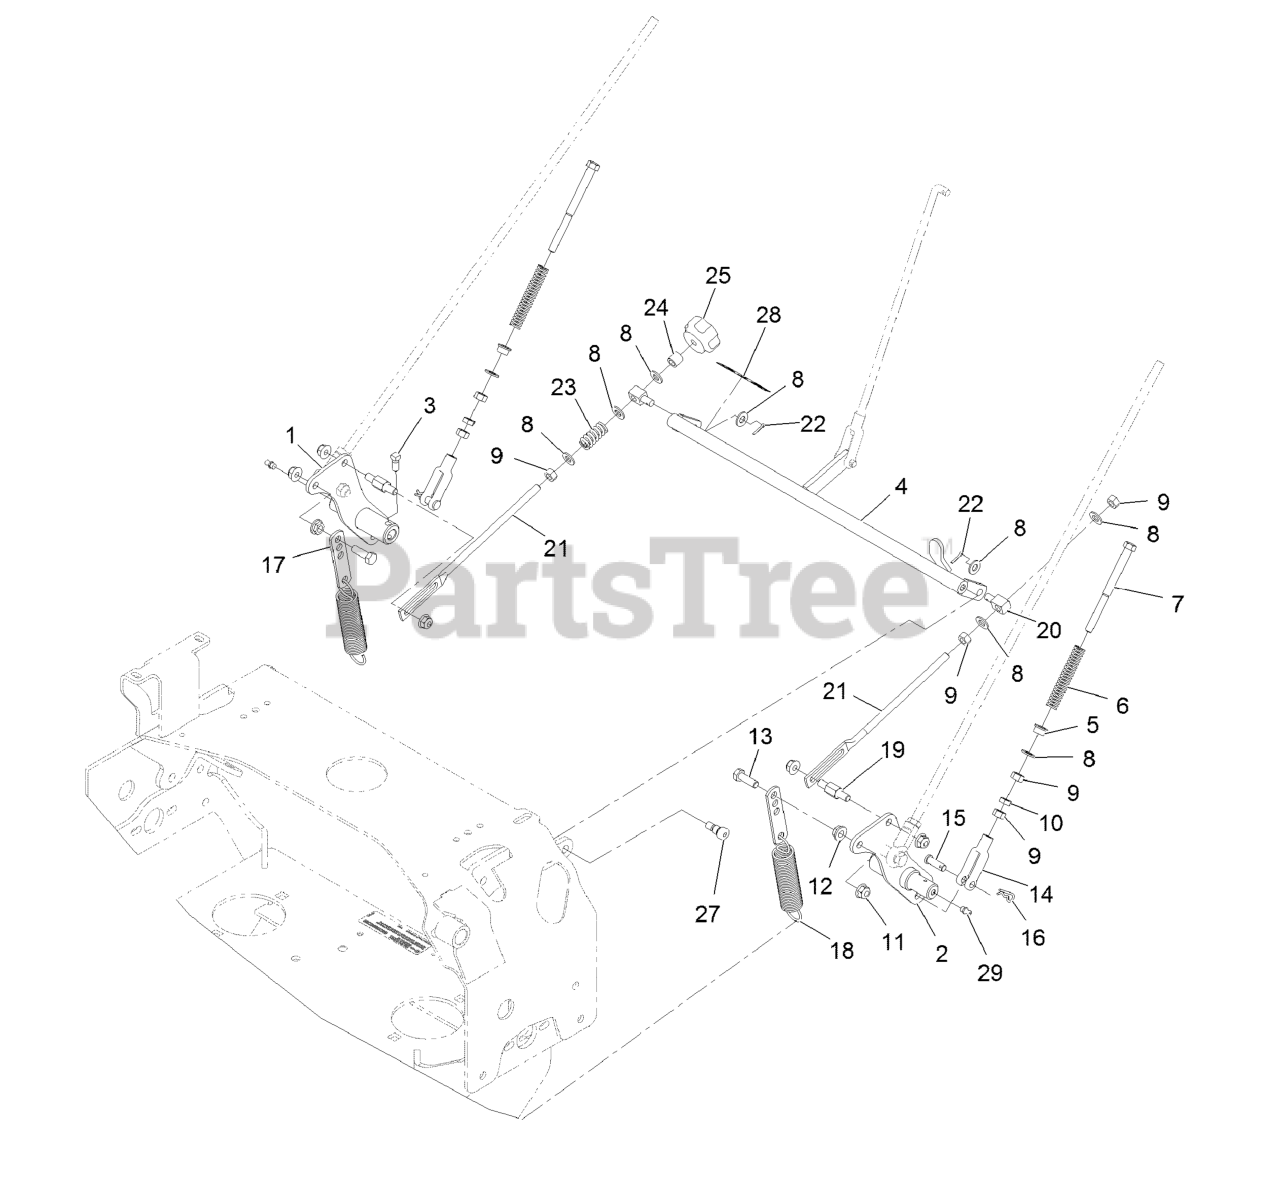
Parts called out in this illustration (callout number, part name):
1	WELD, MOTION CONTROL, RT
2	WELD, MOTION CONTROL, LT
3	SCREW-SET
4	WELD, SPEED CONTROL
5	BUSHING-FLANGED
6	SPRING,COMPRESSION (NEUT)
7	BOLT-RETURN, NEUTRAL
8	WASHER-PLAIN
9	NUT-HEX
10	NUT-JAM
11	NUT-HF, NI
13	SCREW-HH
14	YOKE-ADJUSTABLE
15	PIN-CLEVIS
16	PIN-COTTER
17	TAB-SPRING, EXTENSION
18	SPRING-EXTENSION
19	PIN, MOTION CONTROL
20	SWIVEL-ADJUSTABLE, SHORT
21	LINK-CONTROL, SPEED
22	PIN-COTTER
23	SPRING-COMPRESSION
25	KNOB-TRACKING
27	SCREW-HSH
28	DECAL-TRACKING ADJUSTMENT
29	FITTING-GREASE
